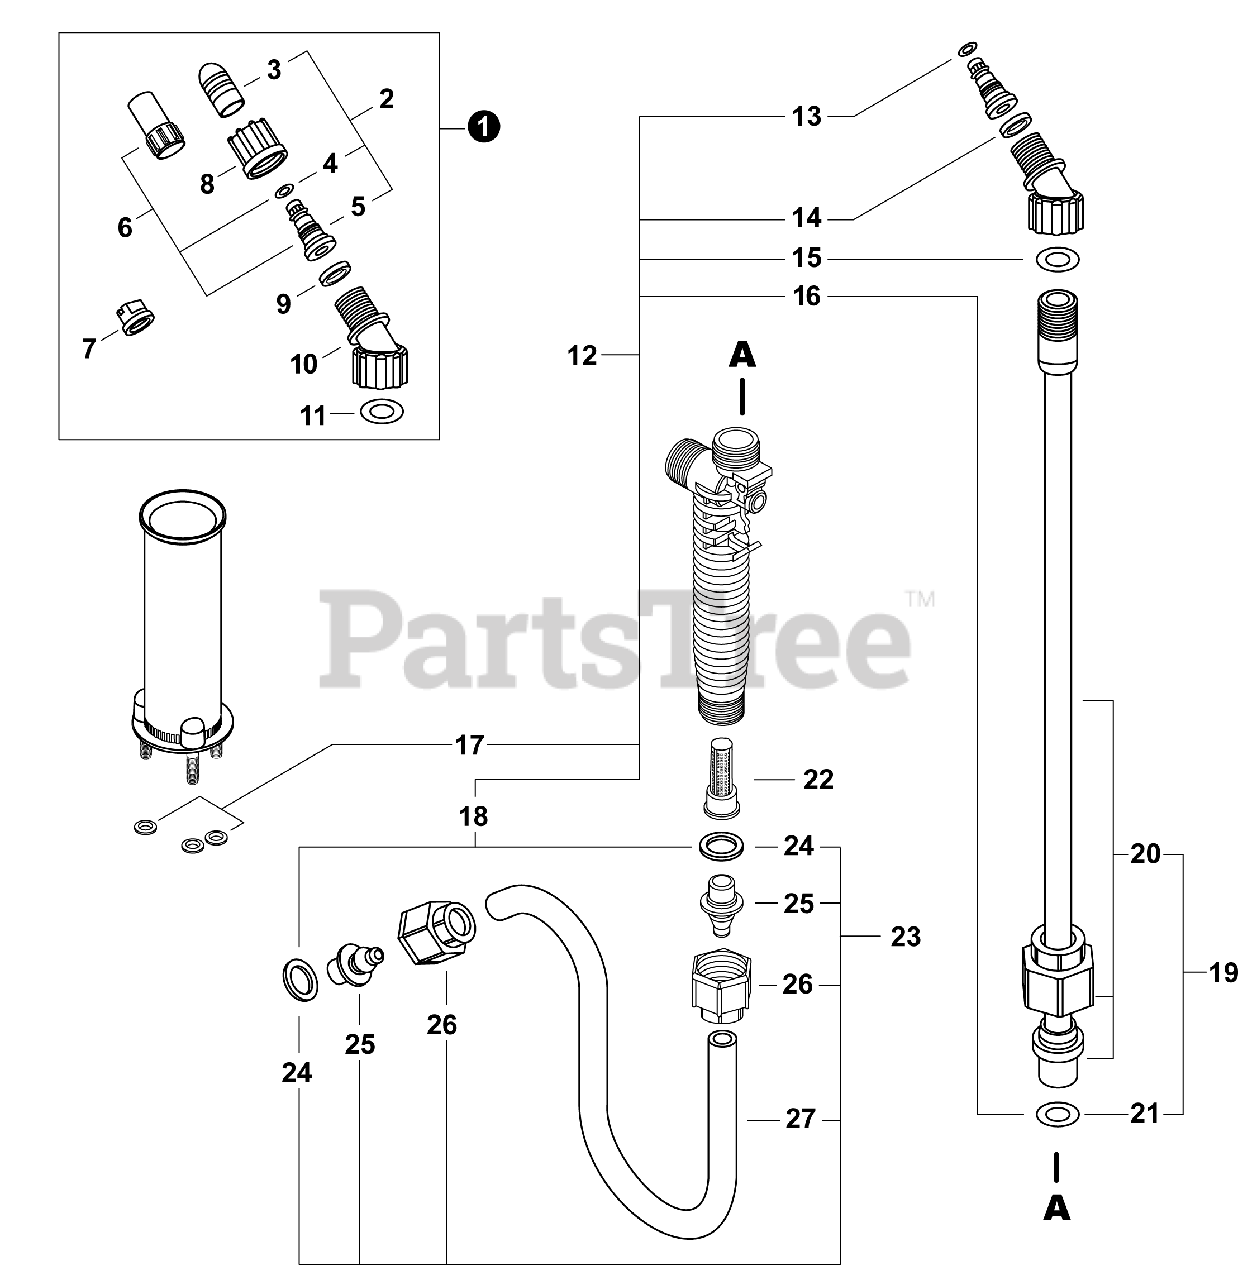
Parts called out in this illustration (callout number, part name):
1	NOZZLE KIT
2	NOZZLE KIT, BRASS
3	CAP, NOZZLE - BRASS
4	O-RING, NOZZLE
5	BODY, NOZZLE
6	NOZZLE KIT, PLASTIC
7	NOZZLE, FLAT FAN
8	NUT, NOZZLE
9	GASKET, NOZZLE
10	ELBOW, NOZZLE
11	O-RING, ELBOW
12	GASKET KIT, BPE
13	O-RING, NOZZLE
14	GASKET, NOZZLE
15	O-RING, ELBOW
17	GASKET, STUD
18	GASKET, ADAPTER
19	WAND ASSY, METAL
22	FILTER, SPRAY GUN
23	HOSE ASSY
24	GASKET, ADAPTER
25	ADAPTER, HOSE - BLACK
26	NUT, HOSE
